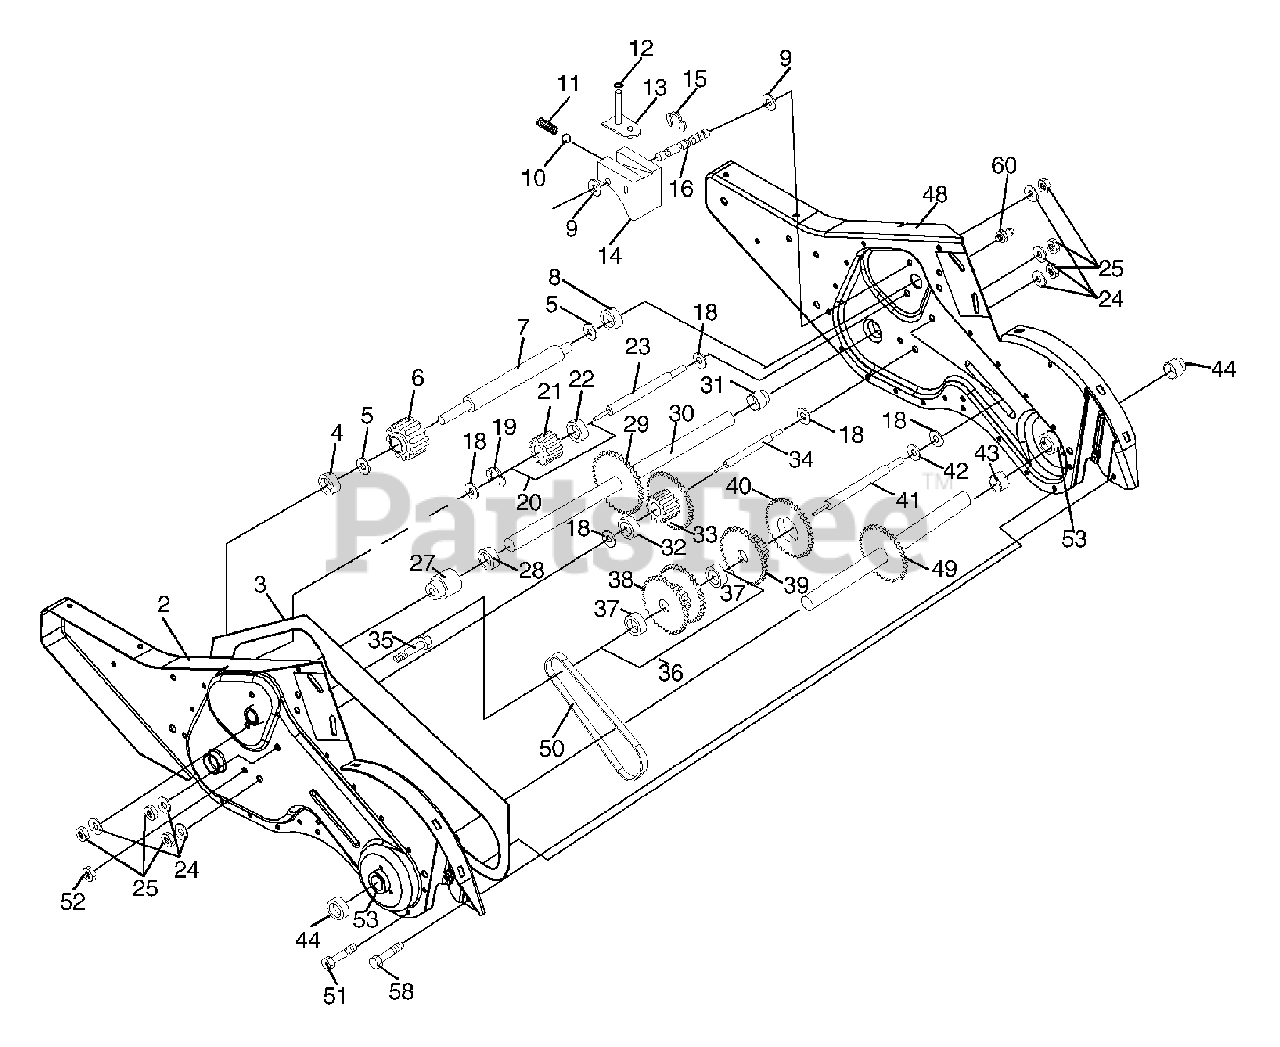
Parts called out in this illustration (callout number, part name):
1	Transmission Assembly
2	Gearcase, L.H. w/Bearing
3	Gasket, Gearcase
4	Bearing, Needle
5	Washer, Thrust 5/8 x 1.10 x 1/32
6	Pinion, Input
7	Shaft, Input
8	Bearing, Needle
9	Washer, Seal
10	Ball, Steel
11	Spring, Shift, Fork
12	O-Ring
13	Bracket, Shift
14	Fork, Shift
15	Ring, Klip
16	Shaft, Shift
18	Washer
19	Ring, Klip
20	Gear, Assembly, Reverse Idler
21	Gear, Reverse Idler
22	Bearing, Needle
23	Shaft, Reverse Idler
24	Washer, Lock 7/16
25	Nut, Hex 7/16-20
27	Bearing, Shaft, Ground Drive L.H.
28	Spacer 0.765 x 1.125 x 1.23
29	Chain #35-50 Pitch
30	Ground Shaft Assembly
31	Bearing, Shaft, Ground Drive R.H.
32	Spacer 0.70 x 1.00 x 1.150
33	Sprocket and Gear Assembly
34	Shaft, Reduction (2nd)
35	Screw, Whiz, Lock 5/16-18 x 3-1/2
36	Sprocket Assembly w/Bearing
37	Bearing, Needle
38	Sprocket, Tine
39	Gear, Cluster, Red 1st & 2nd
40	Gear, Reverse
41	Shaft, Reduction (1st)
42	Washer, Thrust
43	Spacer 1.01 x 1.75 x 0.760
44	Seal, Asm. Oil
48	Gearcase, R.H. w/Bearing
49	Shaft, Tine
50	Chain, Roller #50-50 Pitch
51	Screw 1/4-20 x 1/2
52	Nut, Hex 5/16-18
53	Kit, Bearing, Tine Shaft
58	Bolt Shoulder 1/4-20 x .875
60	Fitting Grease
